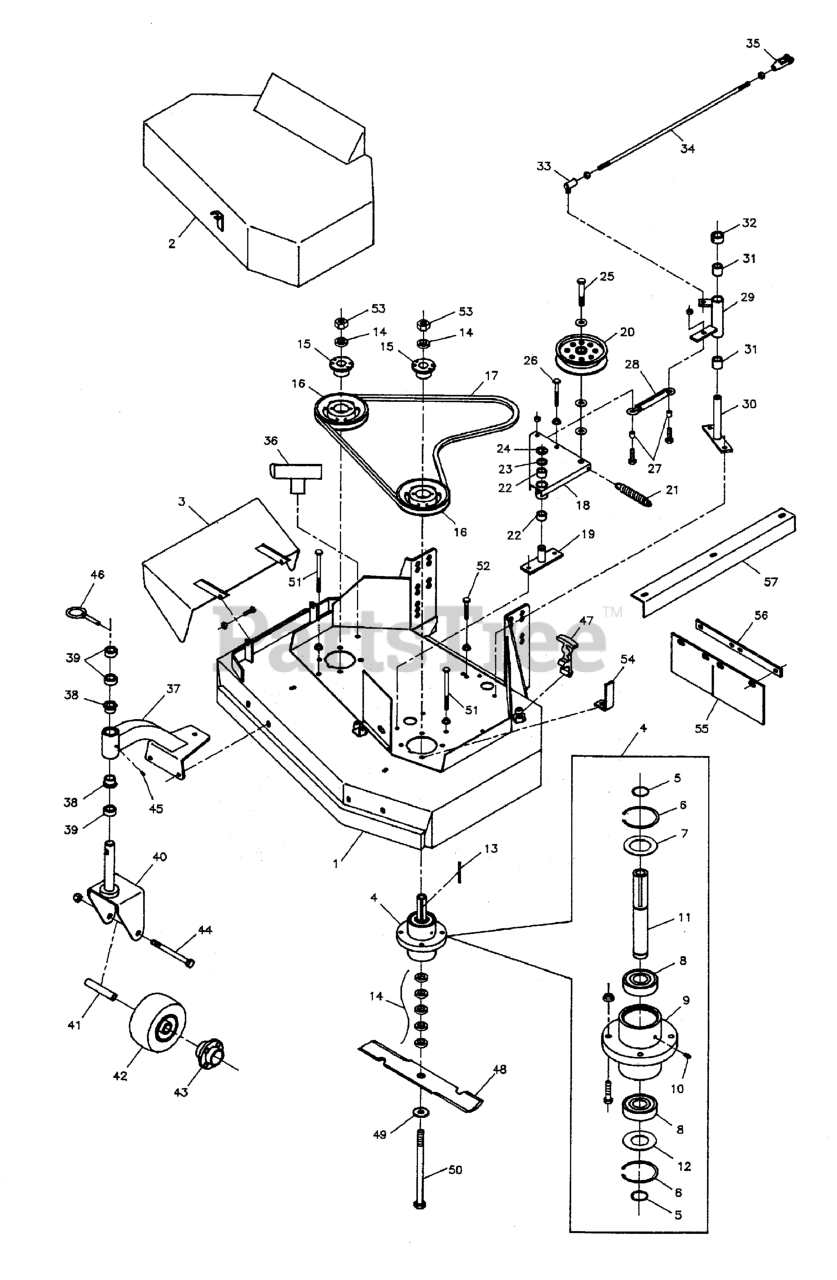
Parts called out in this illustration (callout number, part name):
1	32" MOWER HOUSING ASSEMBLY
1	DECK SHELL W/DECALS, 36" HW36 RD
1	DECK SHELL W/ DECALS, 32" HW32 RD
2	36" Guard
2	GUARD, 36"
2	32" DECK GUARD
3	DISCHARGE CHUTE
4	SPINDLE ASSEMBLY, Complete
5	SNAP RING, External
6	SNAP RING, Internal
7	SPINDLE WASHER, Top
8	BEARING
9	SPINDLE HOUSING
10	GREASE FITTING
11	SPINDLE SHAFT
12	SPINDLE WASHER, Bottom
13	KEY, 1/4 SQ. X 2-1/2
14	SPACER, .63 x 1.06 x .23
15	BUSHING, Tapered Hub
16	PULLEY, Spindle
17	BELT, #7-3030
17	BELT
18	CLUTCH PIVOT PLATE
19	IDLER MOUNT
20	PULLEY, Backside Idler
20	IDLER PULLEY
21	SPRING, Extension
22	BUSHING
23	SHIM
24	C-CLIP
25	BOLT, 1/2-20 x 3
26	BOLT, 3/8-16 X 3" GD5 CZ
27	SLEEVE
28	TURNBUCKLE ASSY
29	BLADE ENGAGE BELL CRANK
30	BLADE ENGAGE PIVOT
31	BUSHING, .75 X 1.00 X 1.00, PLASTIC
32	COLLAR, 3/4" Set
33	BALL JOINT, 3/8" Female Studded
34	ROD, Blade Engage
35	CLEVIS, 3/8-24, Plastic
36	BELT GUIDE
37	CASTER MOUNT, Complete
38	BUSHING, FLANGE
39	SPACER, 1.02 x 1.56 x .50
40	YOKE, Caster
41	AXLE, Caster Wheel
42	WHEEL & TIRE ASSEMBLY, White, 9 x 3.5 x 4, Complete
43	4 BOLT HUB W/ BEARING
44	BOLT, 1/2-13 x 5-1/2
45	GREASE FITTING
46	PIN, Lynch
47	RUBBER LATCH
48	MOWER BLADE, 18"
48	MOWER BLADE, 16-1/4"
49	WASHER, 5/8" USS
50	BOLT, 5/8-11 x 9-1/2
51	BOLT, 3/8-16 x 5
52	BOLT, 3/8-16 X 2-1/4" GD5 CZ
53	NUT, 5/8-11 Hex
54	BELT GUIDE
55	RUBBER FLAP
56	Flap Support
57	Rear Discharge Baffle 36"
57	BAFFLE, 32"
